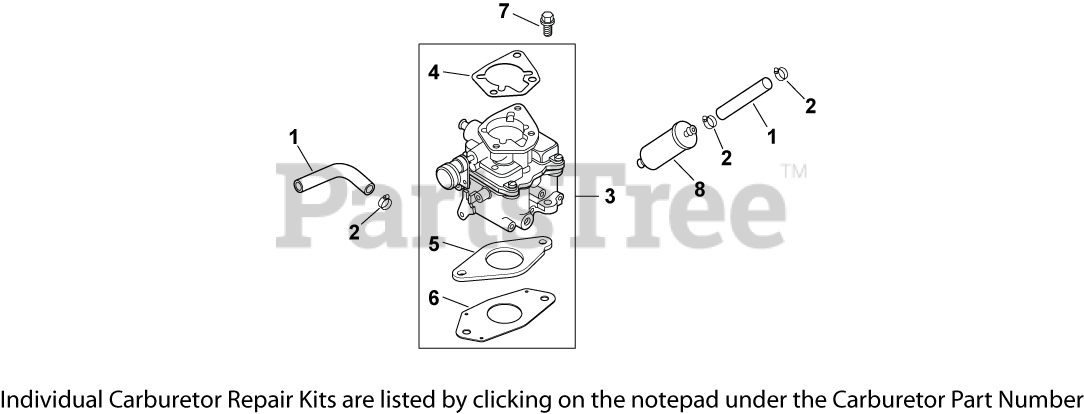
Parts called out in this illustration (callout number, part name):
1	HOSE,LW PERM.FUEL 24.00"-USE 25 111 81-S
2	CLAMP, HOSE (KM)-USE 25 237 31-S
3	KIT, CARBURETOR W/GASKETS
4	GASKET, AIR CLEANER BASE
5	GASKET, CARBURETOR
6	GASKET, CARBURETOR
7	SCREW, FLG M6X1.0X25
8	FILTER, FUEL
